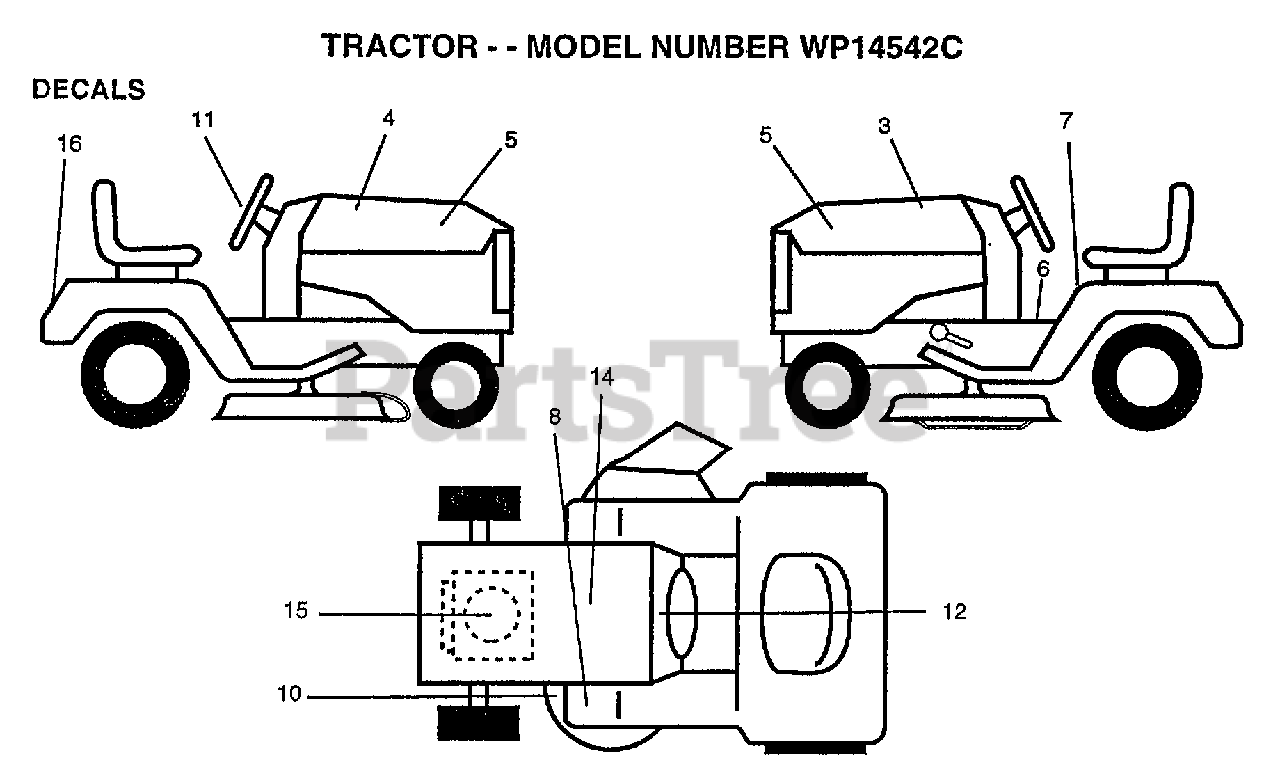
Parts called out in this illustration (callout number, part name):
3	DECAL.HOOD.RH
4	DECAL.HOOD.LH
5	DECAL.INS.HD.LT.
6	DECAL BRAK PARK
7	DECAL
10	DECAL
11	DECAL, INSERT
12	"DECAL-OPER,GEAR D"
14	DECAL.BATRY.3-3908
15	DECAL, ENGINE
16	DECAL, FENDER LOGO
